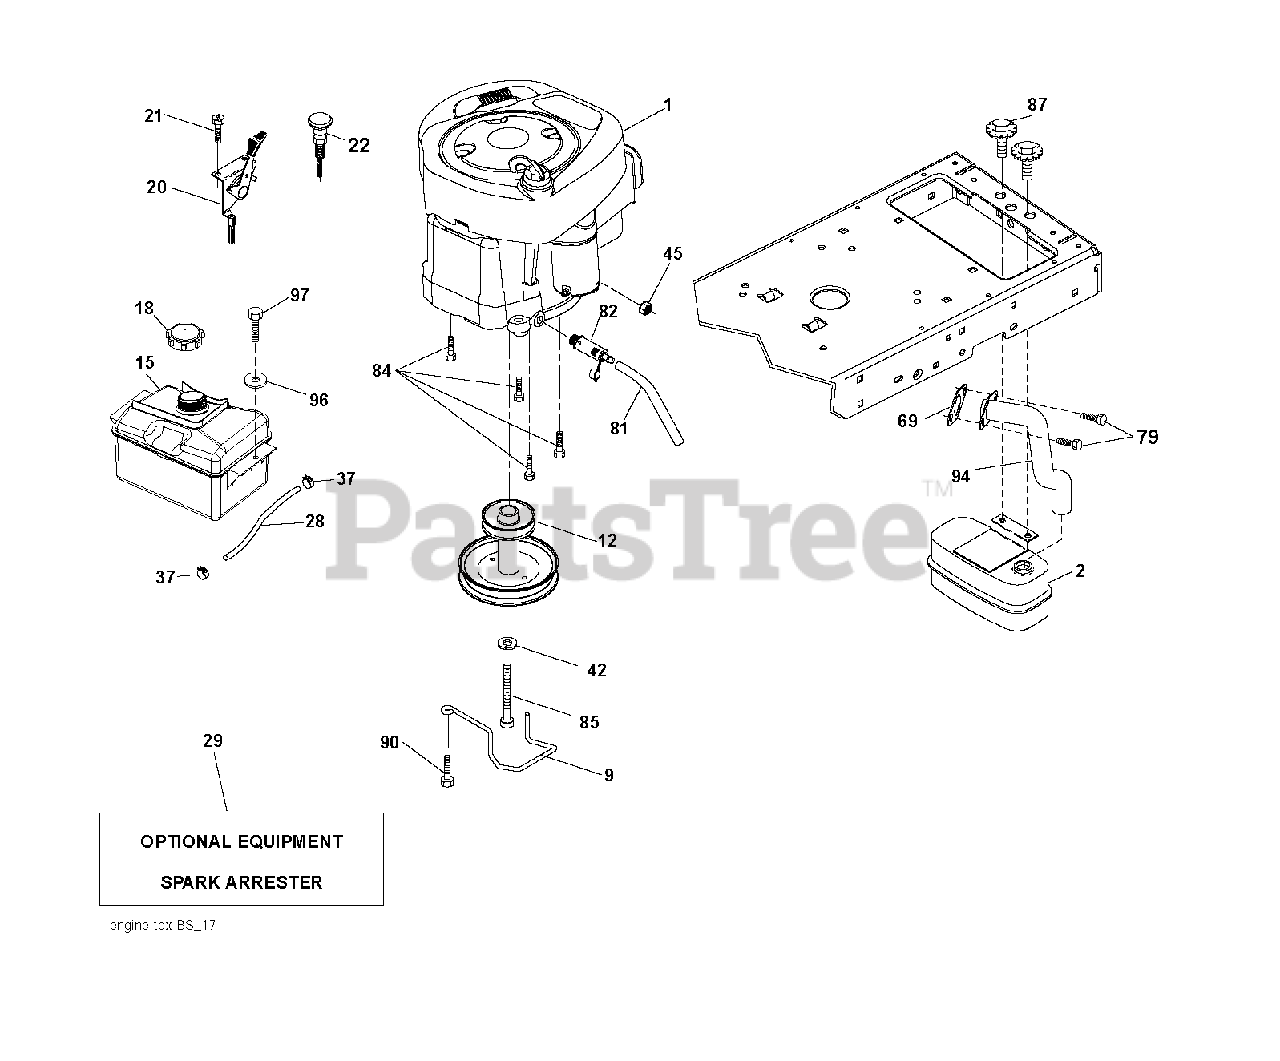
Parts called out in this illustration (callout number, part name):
2	MUFFLER.SINGLE.CYL.KOHL/B&S
9	KEEPER.BELT.ENGINE.3.25
12	PULLEY ENGINE
15	TANK FUEL FRT 1.5 GAL
18	FUEL CAP
20	CONTROL.TH/CK.C.
21	SCREW.#10 X 0.750.BOS THREAD
28	LINE.FUEL.20
29	ARRESTER SPARK (OPTIONAL)
37	HOSE CLAMP
42	LOCKWASHER
45	NUT
69	REPL BY 532 27 22-93
79	SCREW.SOCKET HD.5/16-1
81	TUBE, DRAIN OIL ASM.
82	PLUG DRAIN OIL EASY
84	SCREW.3/8-16
85	BOLT HEX 7/16-20X4-1/4"
87	BOLT, 5/16-18 X 1 3/4
90	SCREW 3/8-16X1
94	EXHAUST.TUBE.B&S.
97	SCREW HEXWSHR 1/4-20X3/4
